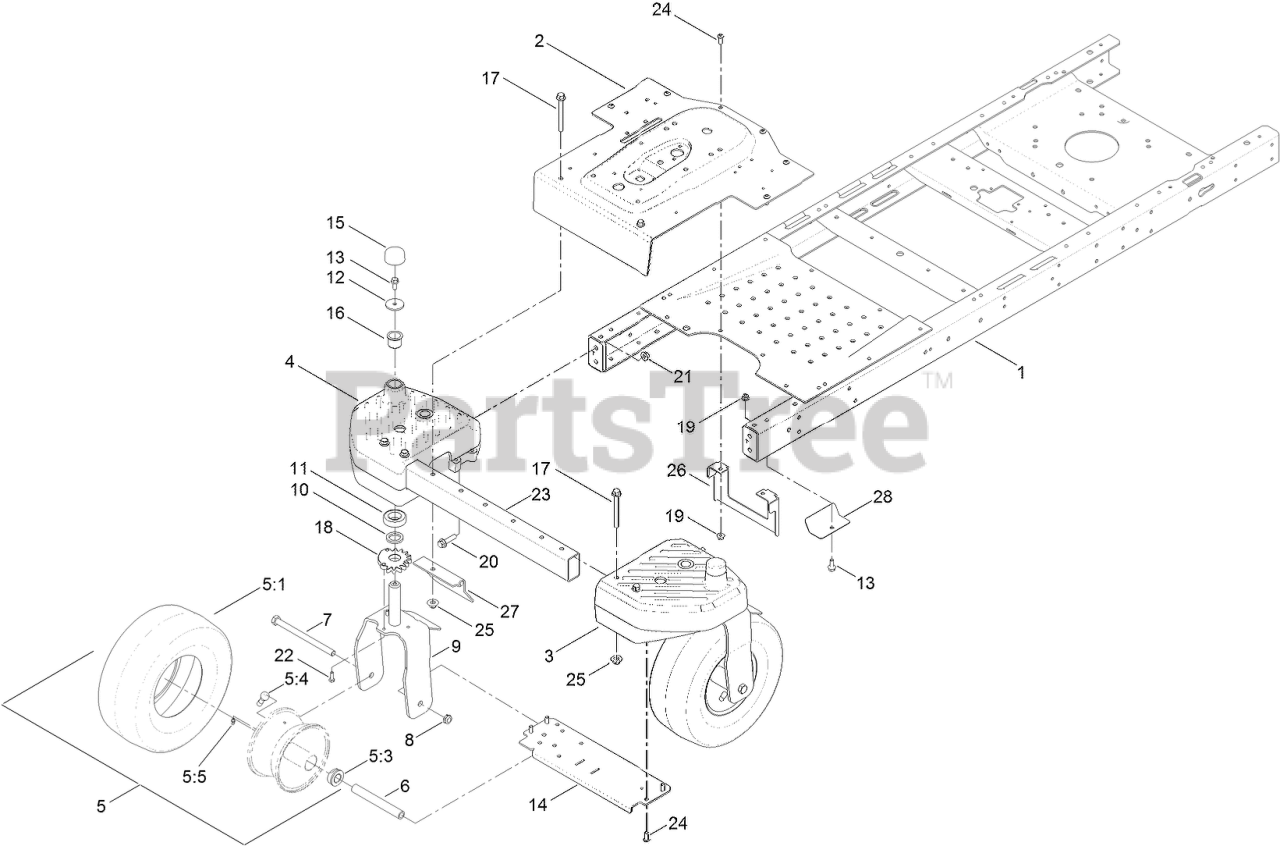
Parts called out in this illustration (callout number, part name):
1	FRAME ASM
2	PAN-STEER, FRONT
3	HOUSING-SPINDLE, LH
4	HOUSING-SPINDLE, RH
5	13 INCH WHEEL AND TIRE ASM
5:1	TIRE-13 Inch
5:3	BUSHING-FLANGE
5:4	STEM-VALVE
5:5	FITTING-GREASE
6	SPANNER
7	SCREW-HH
8	NUT-LOCK, NI
9	CASTER FORK ASM
10	WASHER-THRUST
11	BEARING-BALL
12	WASHER-FLAT
13	SCREW-HHF
14	PLATE-BRIDGE, NARROW
15	CAP-CASTER
16	BUSHING-PIVOT
17	SCREW-HHF
18	GEAR-WHEEL, 15 TEETH
19	NUT-HF, NI
20	SCREW-HHF
21	NUT-HF, NI
22	SCREW-HH
23	TUBE-FRONT, NARROW
24	SCREW-HSBH
25	NUT-FLANGE, NI
26	BRACKET-UPSTOP
27	GUARD-FRONT
28	PLATE-GUARD
